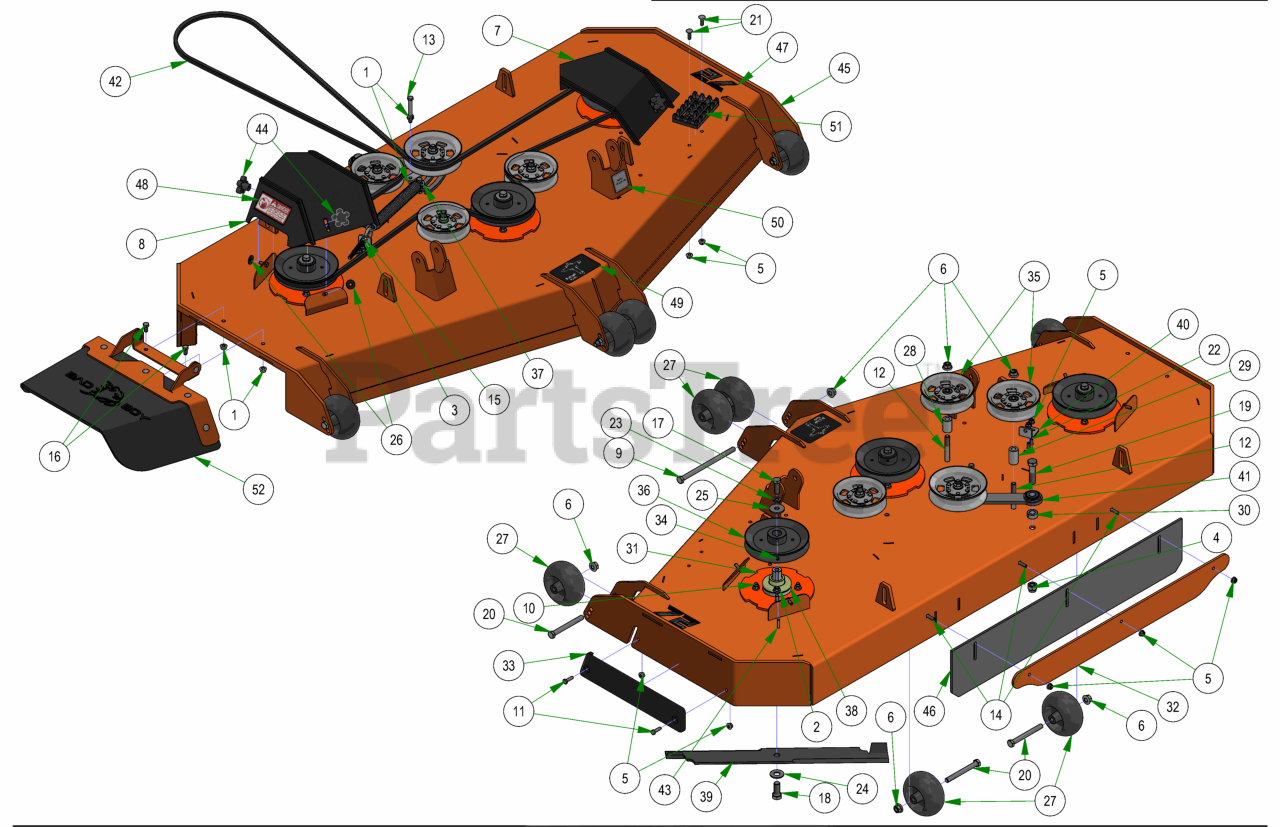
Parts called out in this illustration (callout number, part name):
1	3/8-16 HEX SERRATED FLANGE NUT HARD/ZINC
2	3/8-16 NYLON INSERT FLANGE LOCKNUT (GR.F) ZINC
3	3/8-16 HEX NUT ZINC
4	5/8-11 NYLON INSERT LOCKNUT ZINC
5	5/16-18 NYLON INSERT FLANGE LOCKNUT ZINC
6	1/2-13 NYLON INSERT FLANGE LOCKNUT ZINC
7	Pulley Cover LH Rebel, Rogue, Renegade 72"
8	Pulley Cover RH Rogue, Rebel, Renegade 72"
9	1/2-13 X 8 HEX CAP SCREW GR 5 ZINC
10	3/8-16 X 1-3/4 HEX C/S (GR.5) ZC
11	5/16-18 X 1 HEX CAP SCREW (GR.5) ZINC
12	1/2-13 X 3-1/2 HEX FLANGE BOLT (GR.8) ZINC
13	3/8-16 X 3 HEX CAP SCREW (GR.5) ZINC
14	5/16-18 X 1-1/4 CARRIAGE BOLT ZINC
15	4" 3/8-16 Eye Bolt
16	3/8-16 X 3/4 HEX CAP SCREW (GR.5) ZINC
17	1/2-20 X 1-1/2 HEX CAP SCREW (GR.5) ZINC
18	5/8-18 X 1-1/2 HEX CAP SCREW (GR.8) ZINC YELLOW
19	5/8-11 X 2-1/2 HEX CAP SCREW (GR.5) ZINC
20	1/2-13 X 4-1/2 HEX CAP SCREW (GR.5) ZINC
21	5/16-18 X 1 CARRIAGE BOLT (GR.8) ZINC
22	5/16-18 X 7/8 CARRIAGE BOLT ZINC
23	1/2 SPLIT LOCKWASHER (GR.8) ZINC/YELLOW
24	5/8 USS FLAT WASHER (1-3/4" OD) GR.8 ZINC YELLOW
25	1/2 BELLEVILLE WASHER (1-5/8 OD X .140 THK) ZINC
26	.360 ID X .983 OD X .120 THICK FLAT WASHER NYLON BLACK
27	2019 Deck Wheel
28	.502 ID X .750 OD X 1.500 Long Spacer
29	1 3/4" Pulley Spacer
30	5/8 SOLID SHAFT COLLAR (W/1 SET SCREW) ZINC
31	Deck Spindle Support Plate
32	61 Bolt in Baffle Deck v2 Stripping Plate
33	REVISED TRIM BUMPER_20180226
34	5/16-24 X 1/4 SOCKET SET SCREW (CUP PT) PLAIN
35	5-3/4 Idler Pulley
36	7" Deck Pulley
37	2019 Outlaw Gen2 Deck Spring
38	OUTLAW SPINDLE ASSEMBLY
39	72" High Lift Fusion Blade
40	2019 Deck Eye Bolt Tab
41	2019 Rebel Rogue Deck Idler
42	B202 Belt for 72" Outlaw
43	1/4 X 1 SQ MACHINERY KEY 1018 STL PLN
44	5/16" Knob
45	2019 Sloped 72" Deck
46	R Series Rubber For Deck
47	72" Deck Decal
48	Danger Decal-Spindle/Discharge
49	2019 Rebel & Rogue Deck Belt Route Decal
50	Deck Impact Patent Decal 9591803
51	Deck Step Assembly
52	2019 Outlaw Gen2 Chute Assembly
